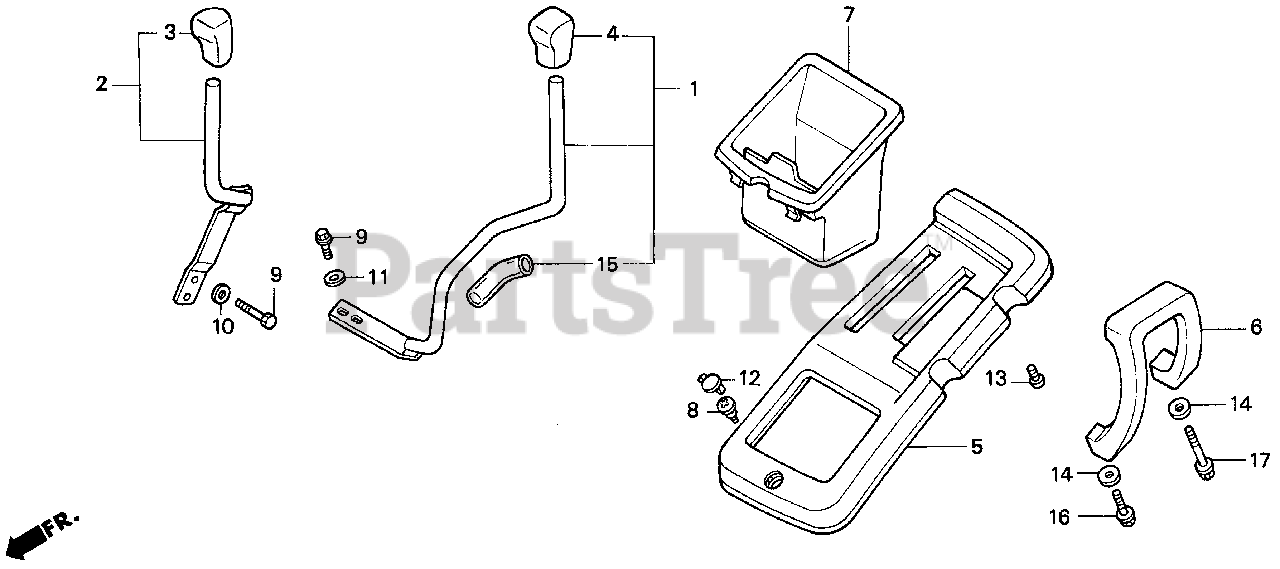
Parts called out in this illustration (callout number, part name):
1	LEVER, AUXILIARY CHANGE
2	LEVER, P.T.O. CHANGE
3	KNOB, P.T.O. CHANGE LEVER
4	KNOB, AUXILIARY CHANGE LEVER
5	PANEL, L. CONTROL *NH247R* (ASSEMBLY GRAY)
6	GRIP, L. *NH247* (ASSEMBLY GRAY)
7	POCKET, CONTROL *NH247* (ASSEMBLY GRAY)
8	SCREW, VISOR SPECIAL SETTING
9	BOLT, SPECIAL (8X25)
10	WASHER, CONICAL SPRING (8MM)
11	WASHER, PLAIN (8X23X3.2)
12	CAP, LINING *NH120L* (STAR BLACK)
12	CAP, LINING *NH1L* (BLACK)
13	SCREW, PAN (5X8)
14	WASHER, PLAIN (8MM)
15	BULK HOSE, VACUUM (14X1000) (14X100)
16	BOLT, FLANGE (8X38)
17	BOLT, FLANGE (8X55)
